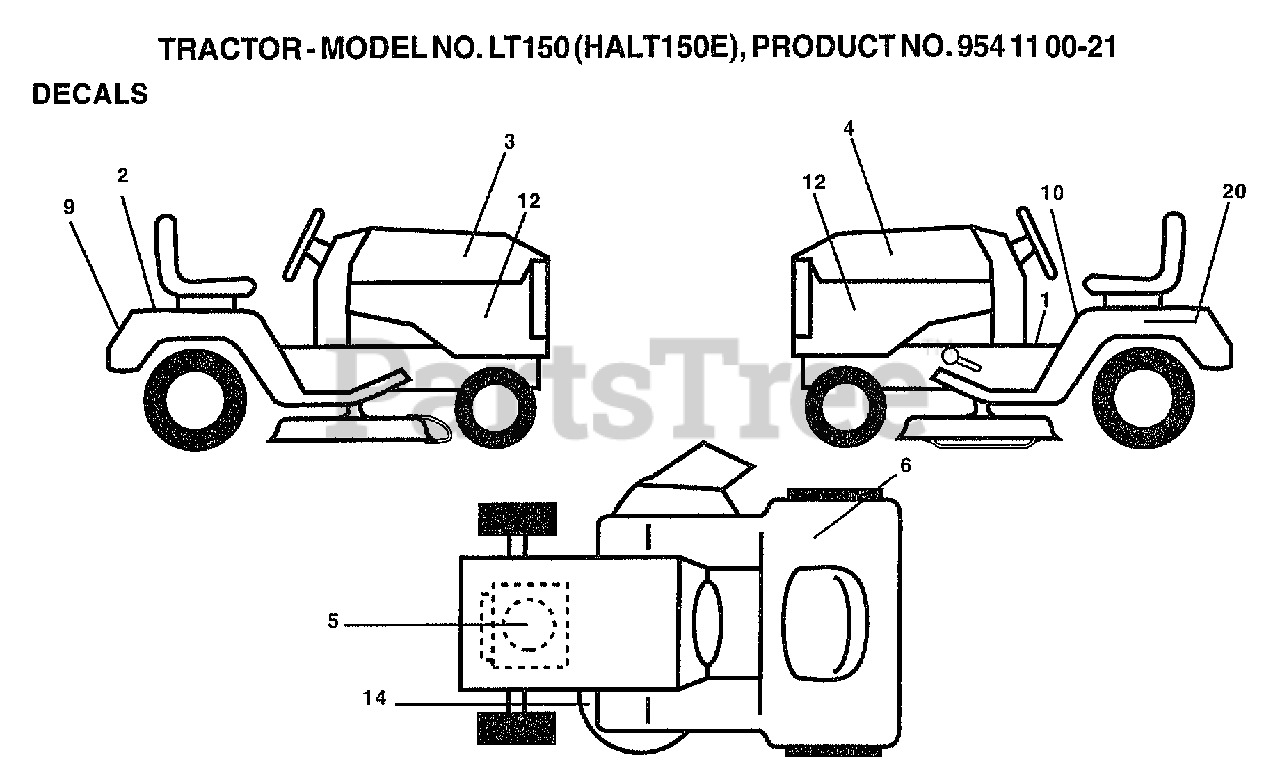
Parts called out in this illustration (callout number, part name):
1	DECAL.FENDER.ST.LT.OPER.INST
2	DECAL, TICK MARK
3	"DECAL HOOD,RH"
4	"DECAL HOOD,LH"
5	DECAL, HP ENGINE
9	DECAL.FENDER.
10	"DECAL-FENDER,DANG"
14	"DECAL-SCHEM,BELT"
